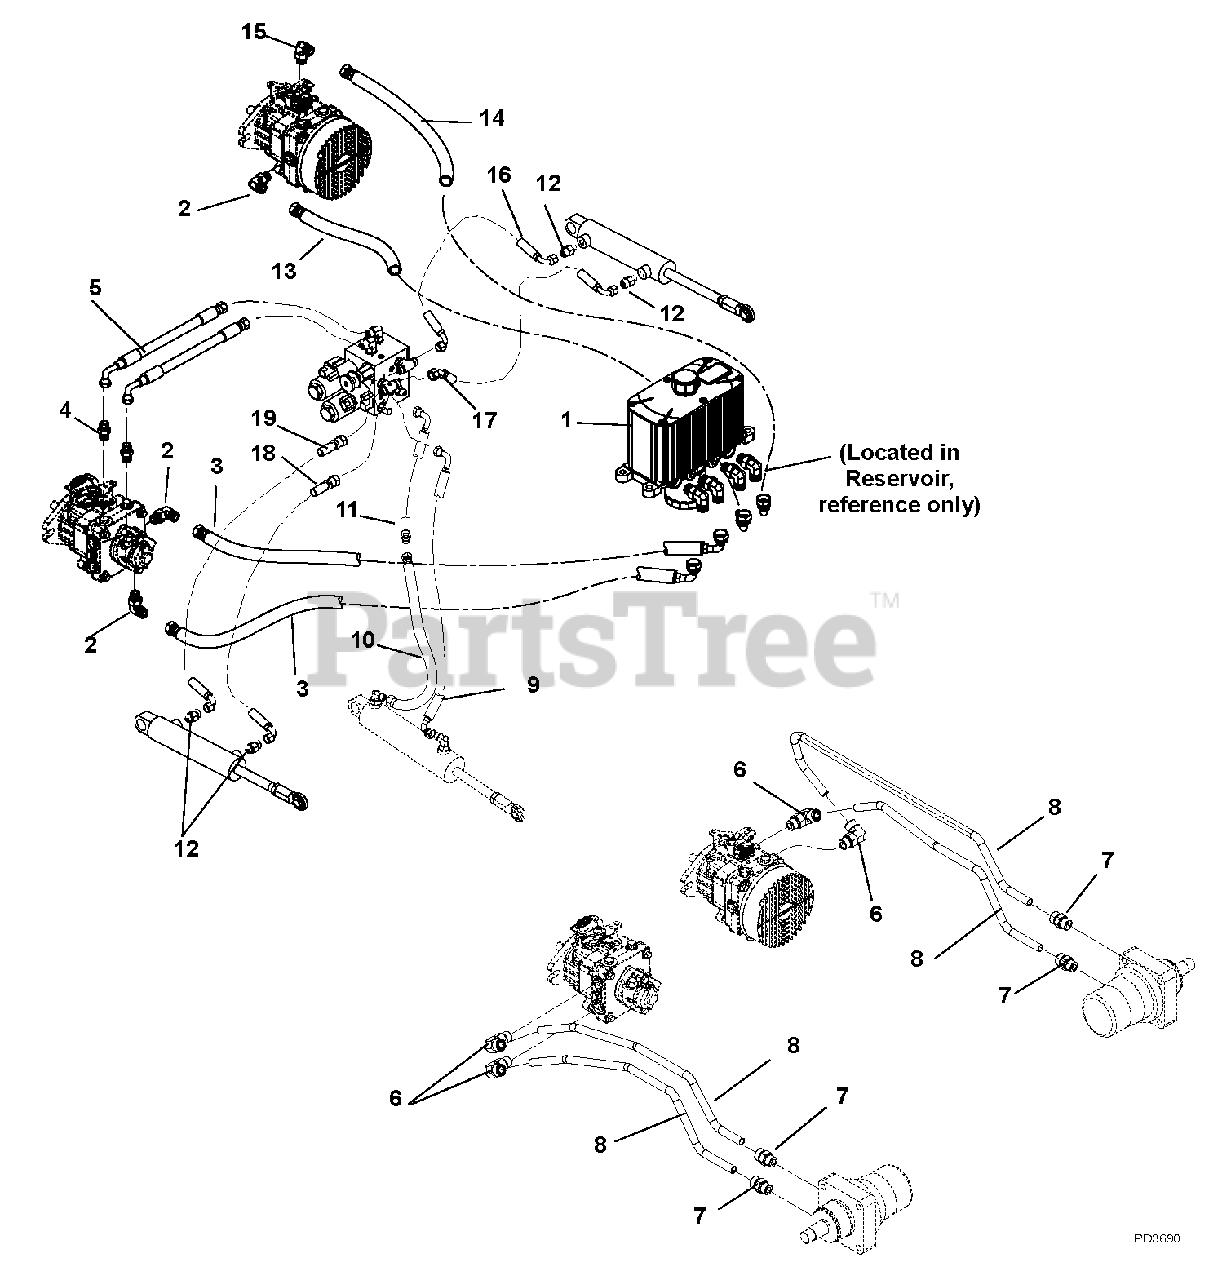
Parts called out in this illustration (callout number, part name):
1	Tank, Hydraulic Reservoir/Filter
2	Fitting, Hydraulic 90 Elbow M8F-M8O 8 C5OLO-Steel
3	Hose, Hydraulic .50-15-0K F08F0-F08F9
4	Fitting, Hydraulic
5	Hose, Hydraulic
6	Fitting, Hydraulic 90 M10F-M8O
7	Fitting, Hydraulic Straight M10O-M10F
8	Hose, Hydraulic .50-25-2K F10F0-F10F0
9	Hose, Hydraulic .25-39-2K F04F0-F04F0
10	Hose, Hydraulic .25-16-2K F04F0-F04F9
11	Hose, Hydraulic .25-20-2K F04F9-F04F9
12	Fitting, Hydraulic 6-4 F5OLO
13	Hose, Hydraulic .5-17.25-0K F8F9-F8F9
14	Hose, Hydraulic .5-17.25-0K F8F9-F8F9
15	Adapter, Face Seal 8 x 8 .50 O-Ring
16	Hose, Hydraulic .38-29-2K F06F9-F06F9
17	Hose, Hydraulic .38-21-2K F06F9-F06F7
18	Hose, Hydraulic .38-32-2K F06F9-F06F0
19	Hose, Hydraulic .38-28-2K F06F9-F06F0
